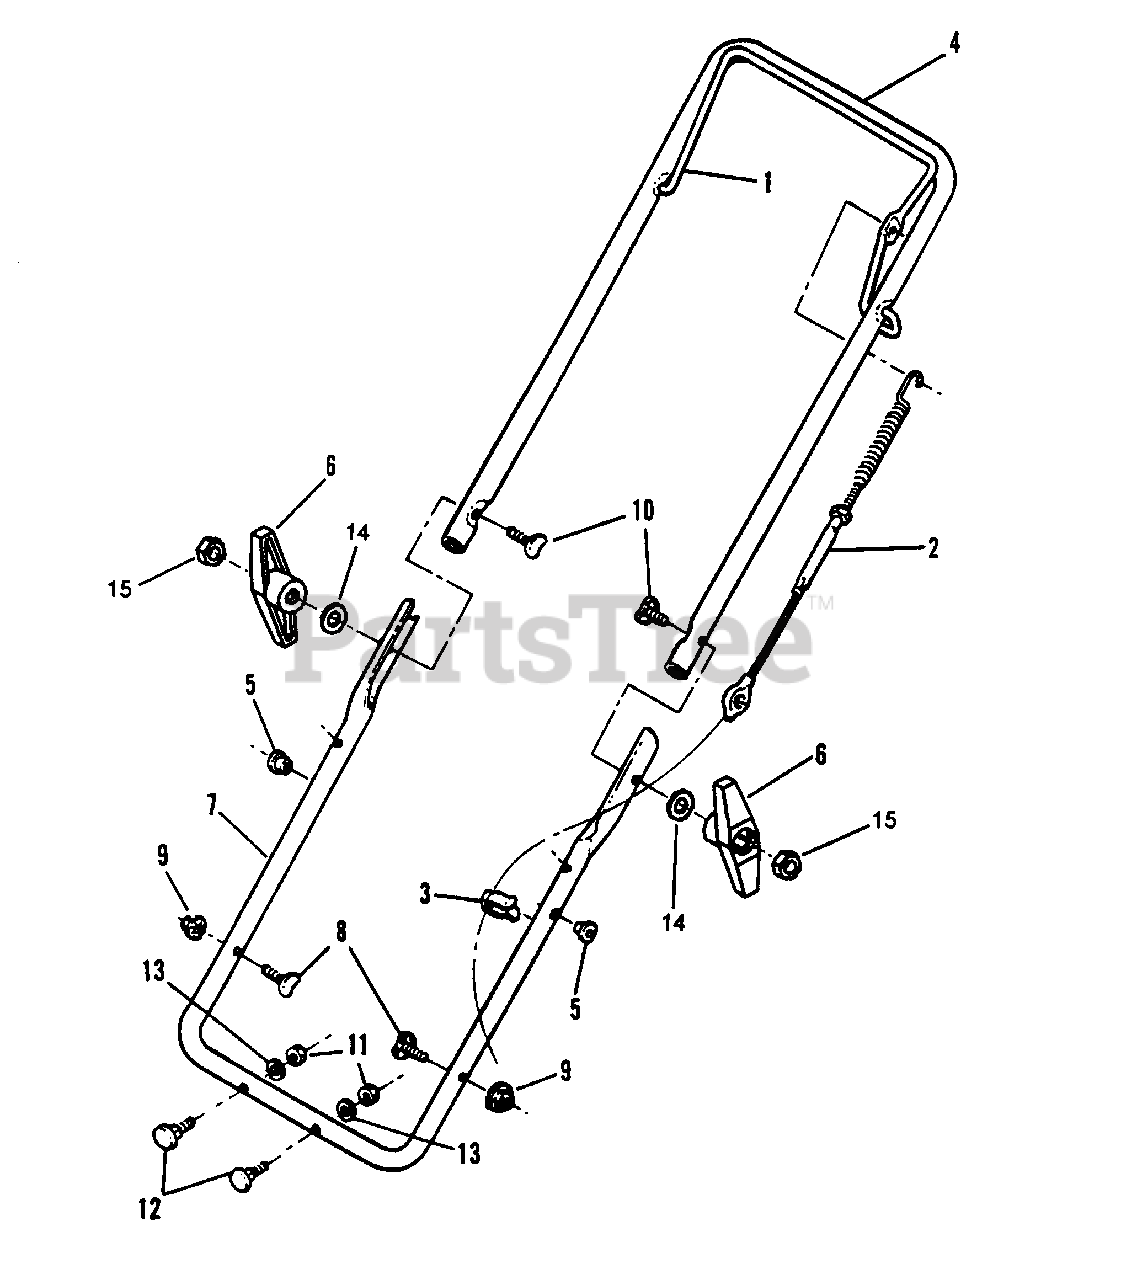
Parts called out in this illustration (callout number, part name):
1	BAIL, Drive Control
2	CABLE, Drive Control
3	CLIP, Wiring Harness
4	HANDLE, Upper
5	INSERT, Nylon
6	T-KNOB, Plastic
7	HANDLE, Lower
8	BOLT, 5/16-18 x 1-3/8" Curved Head
9	NUT, 5/16-18 Hex Flange Lock
10	BOLT, 5/16-18 x 2" Curved Head
11	NUT, 5/16-18 Hex
12	BOLT, 5/16-18 x 1-1/2 Carriage
13	WASHER, 5/16 Split Lock
14	WASHER, 5/16 Flat
15	NUT, 5/16-18 Hex
